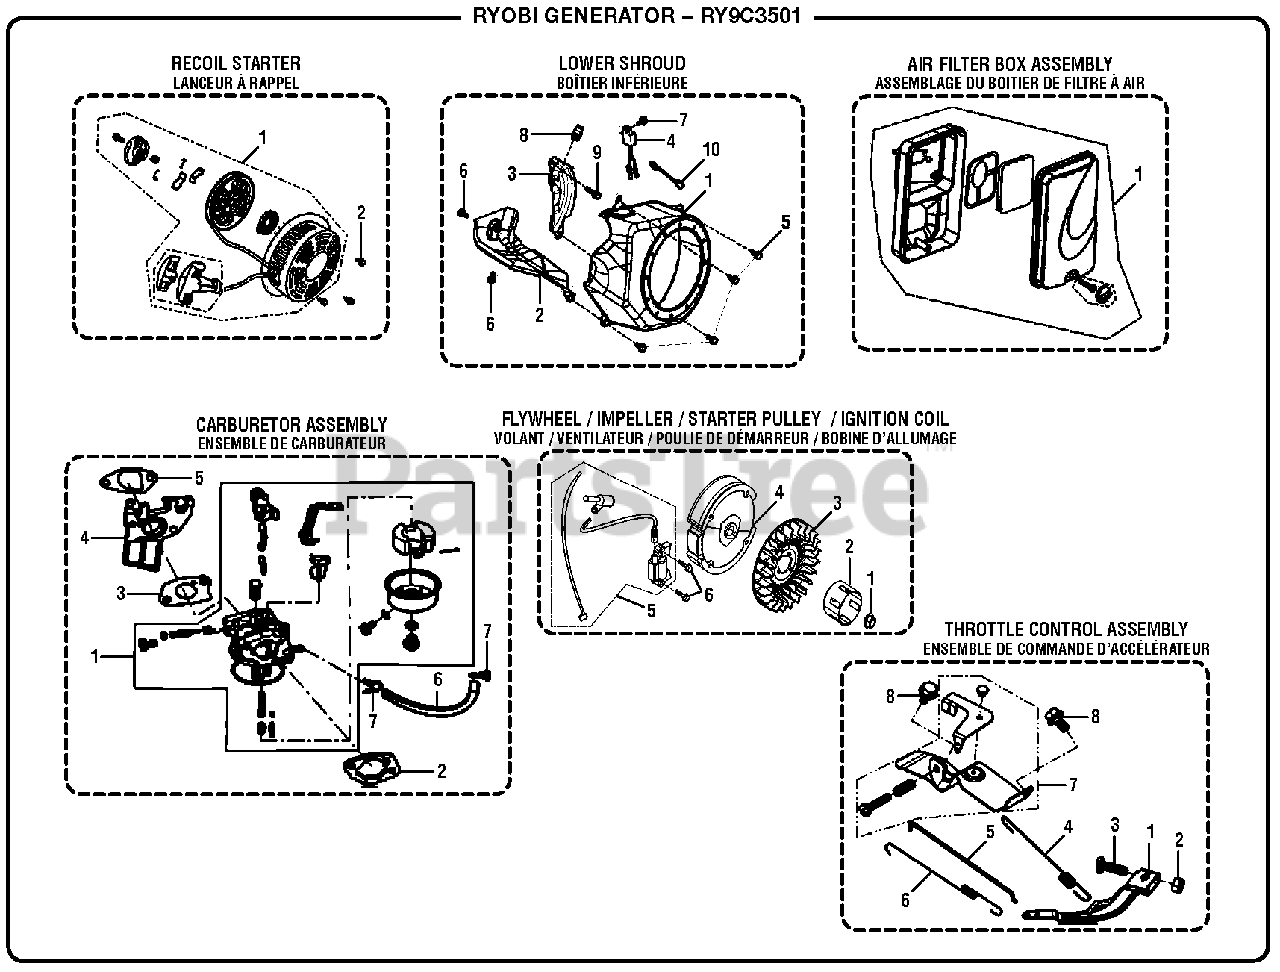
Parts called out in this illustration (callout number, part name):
1	Recoil Starter Assembly
1	Carburetor Assembly
1	Air Cleaner
1	Flywheel Nut
1	Governor Support Assembly
2	Cylinder Body Shroud
2	Air Cleaner Gasket
2	Starter Pulley
3	Lower Shield
3	Carburetor Gasket
3	Impeller
3	Governor Support Bolt
4	Oil Protector
4	Carburetor Insulator Plate
4	Flywheel Assembly
4	Governor Spring
5	Carburetor Insulator Gasket
5	Ignition Coil
5	Governor Rod
6	Throttle Valve Return Spring
7	Clamp
7	Throttle Control Assembly
8	Collar
10	Engine Stop Wire
